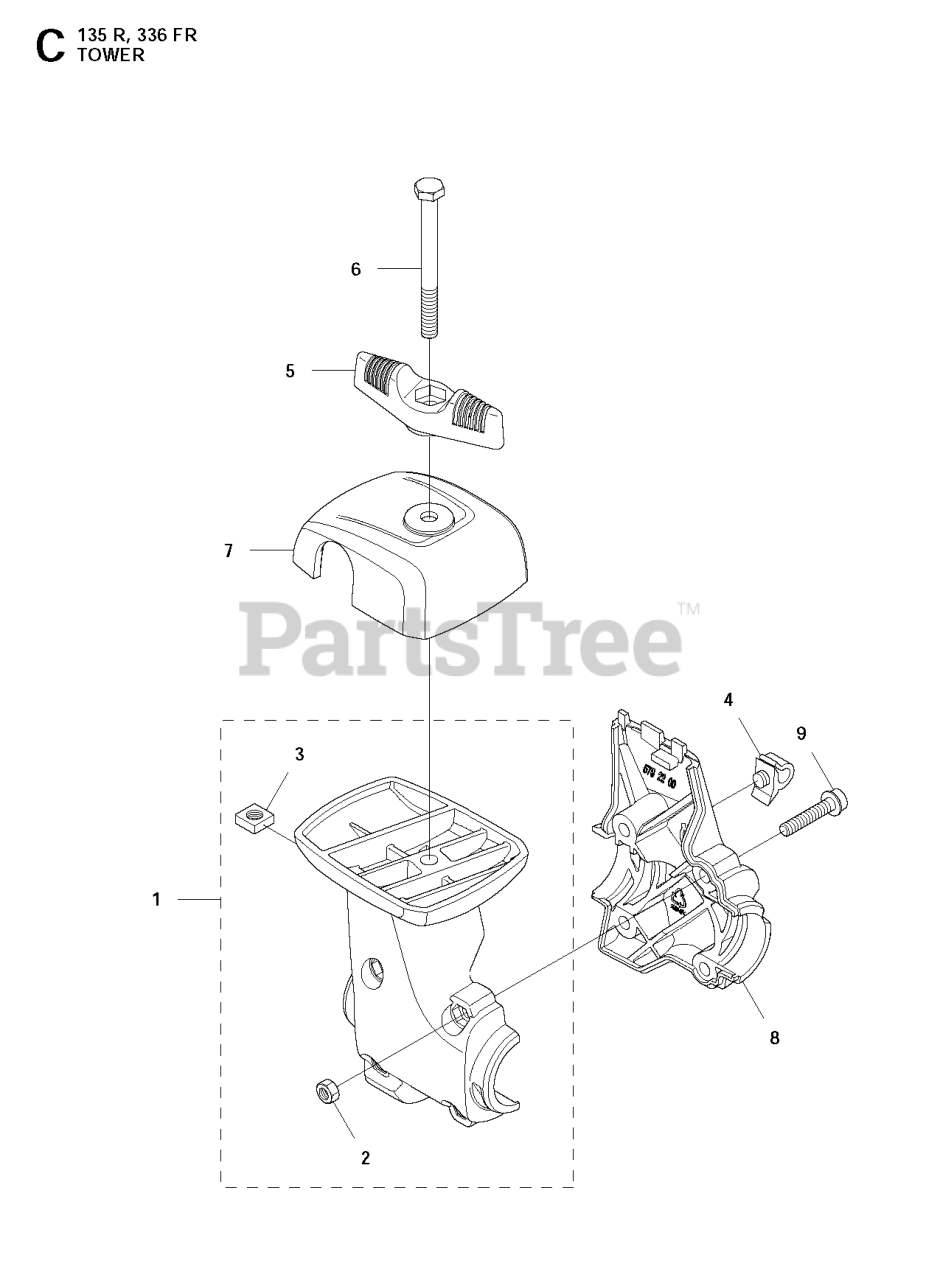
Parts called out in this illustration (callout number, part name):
1	HANDLEBAR BRACKET
6	SCREW EHHM
7	COVER HANDLE BAR
